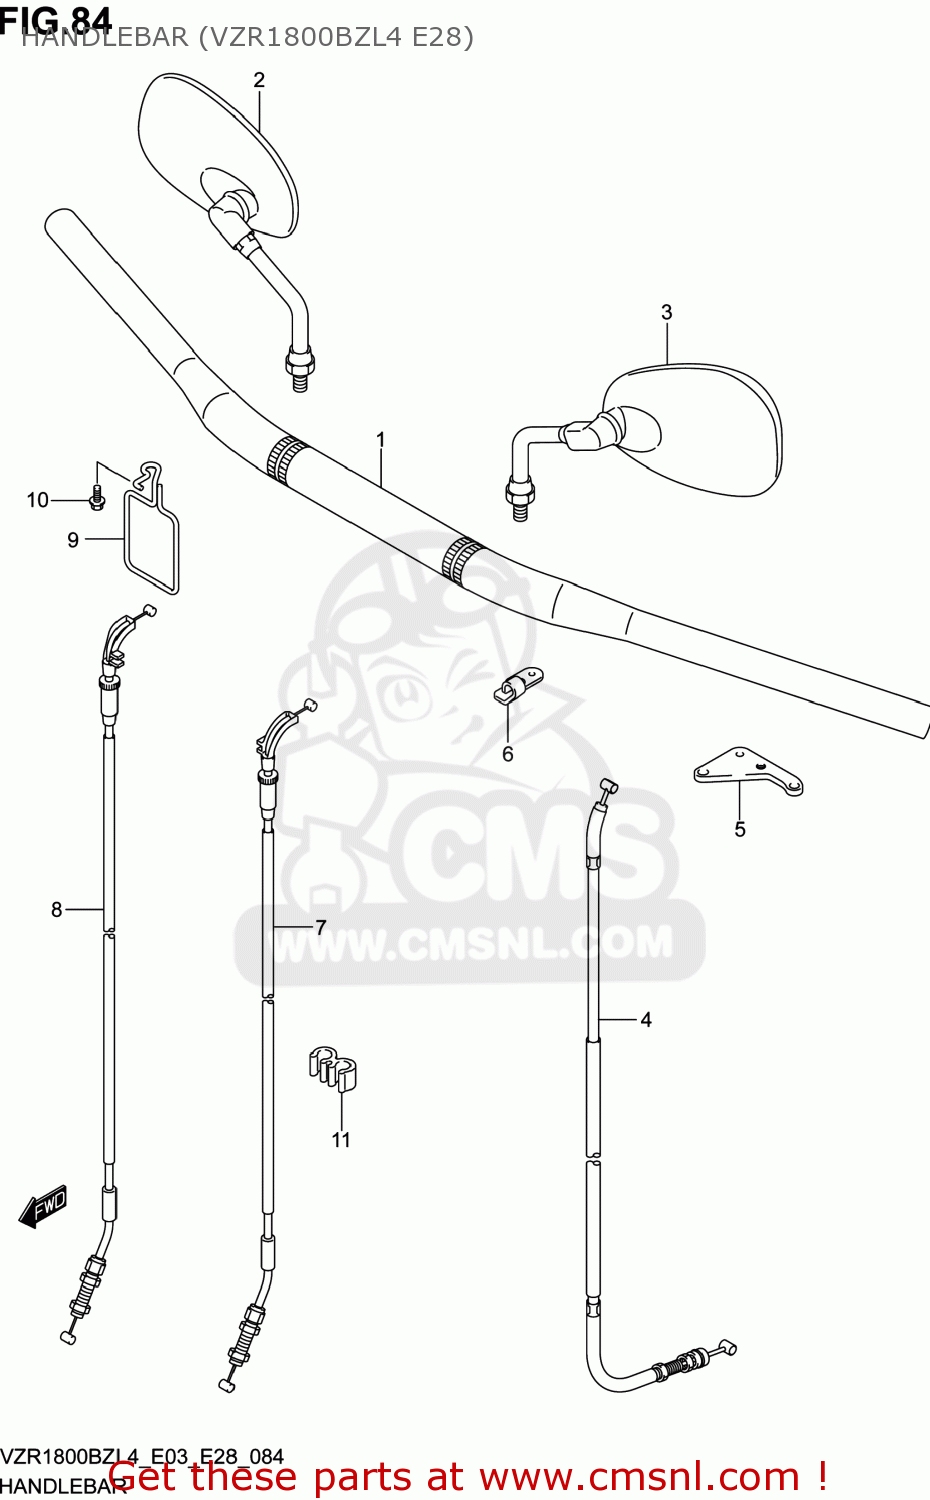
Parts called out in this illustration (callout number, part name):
1	HANDLEBAR
2	MIRROR ASSY,RR VIEW,R
3	MIRROR ASSY,RR VIEW,L
4	CABLE ASSY,CLUTCH
5	STOPPER,CLUTCH CABLE NO.1
6	STOPPER,CLUTCH CABLE
7	CABLE ASSY,THROTTLE NO.1
8	CABLE ASSY,THROTTLE NO.2
9	GUIDE,CABLE NO.2
10	BOLT
11	CLIP
